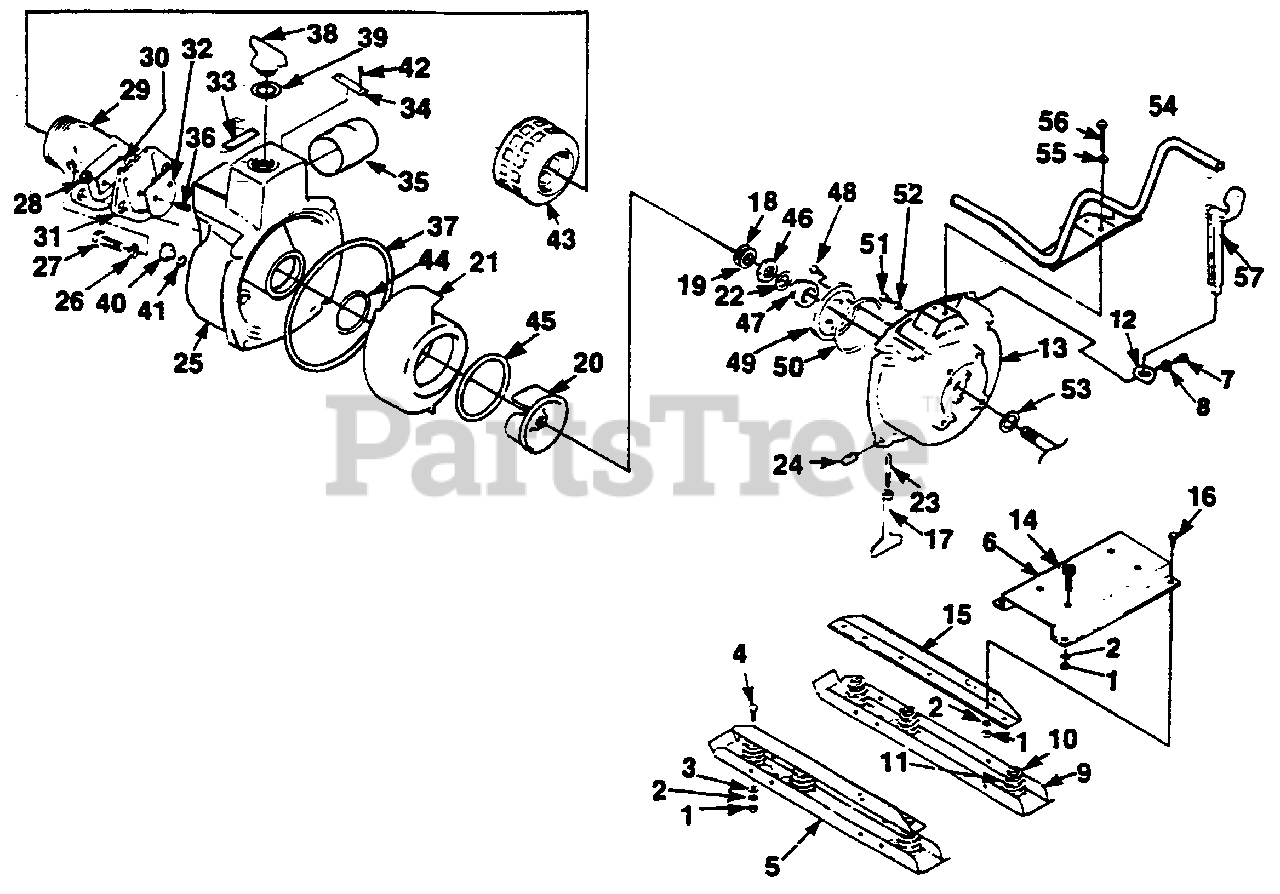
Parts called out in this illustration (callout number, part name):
1	NUT-Hex (5/16-18)
2	WASHER-Lock (5/16)
3	WASHER-Flat (5/16)
4	SCREW-Hex hd. (5/16-18 x 1")
5	ANGLE-Base (Left)
6	BRACKET-Pump engine
7	SCREW-Hex hd. (1/4-20 x 3/8")
8	WASHER-Flat (1/4)
9	SKID-Pump
11	FOOT-Spring
12	BRACKET-Spanner Wrench
13	BODY-Pump
14	SCREW-Hex hd. (5/16-18 x 1 3/4")
15	ANGLE-Base (Right)
16	SCREW-Hex hd. (5/16-18 x 3/4")
17	HANDLE-Disconnect
18	SHIM-Impeller (.032")
19	SHIM (.015")
20	IMPELLER
21	HOUSING-Impeller
22	SHIM-Impeller (.010")
23	STUD-Handle
24	PIVOT-Handle
25	HOUSING-End
26	WASHER-Lock (1/2")
27	SCREW-Cap hex hd. (1/2-13 x 1 1/4")
28	NUT-Hex (10-32)
29	FITTING-Pump suction
30	VALVE-Plate
31	VALVE-Flapper
32	VALVE-Plate
34	PLATE-Warning
36	SCREW (10-32 x 1/2")
37	GASKET-Pump body
38	PLUG-Filler
39	GASKET-Wing nut
40	CAP-Drain & Filler
41	GASKET-Drain & Filler Cap
42	TACK-Metal
43	STRAINER-Suction
44	GASKET-End plate
45	GASKET-Impeller housing
46	NUT-Impeller
47	SEAL-Shaft
48	SCREW-Hex cap (1/4-20 x 5/8")
49	PLATE- Wear
50	"O" RING
51	SCREW-Cap hex hd. (3/8-16 x 1 1/4")
52	WASHER-Slinger
53	SLINGER
54	HANDLE-Carry (3")
55	WASHER-Lock (3/8")
56	SCREW-Cap hex hd. (3/8-16 x 7/8")
57	WRENCH-Spanner
